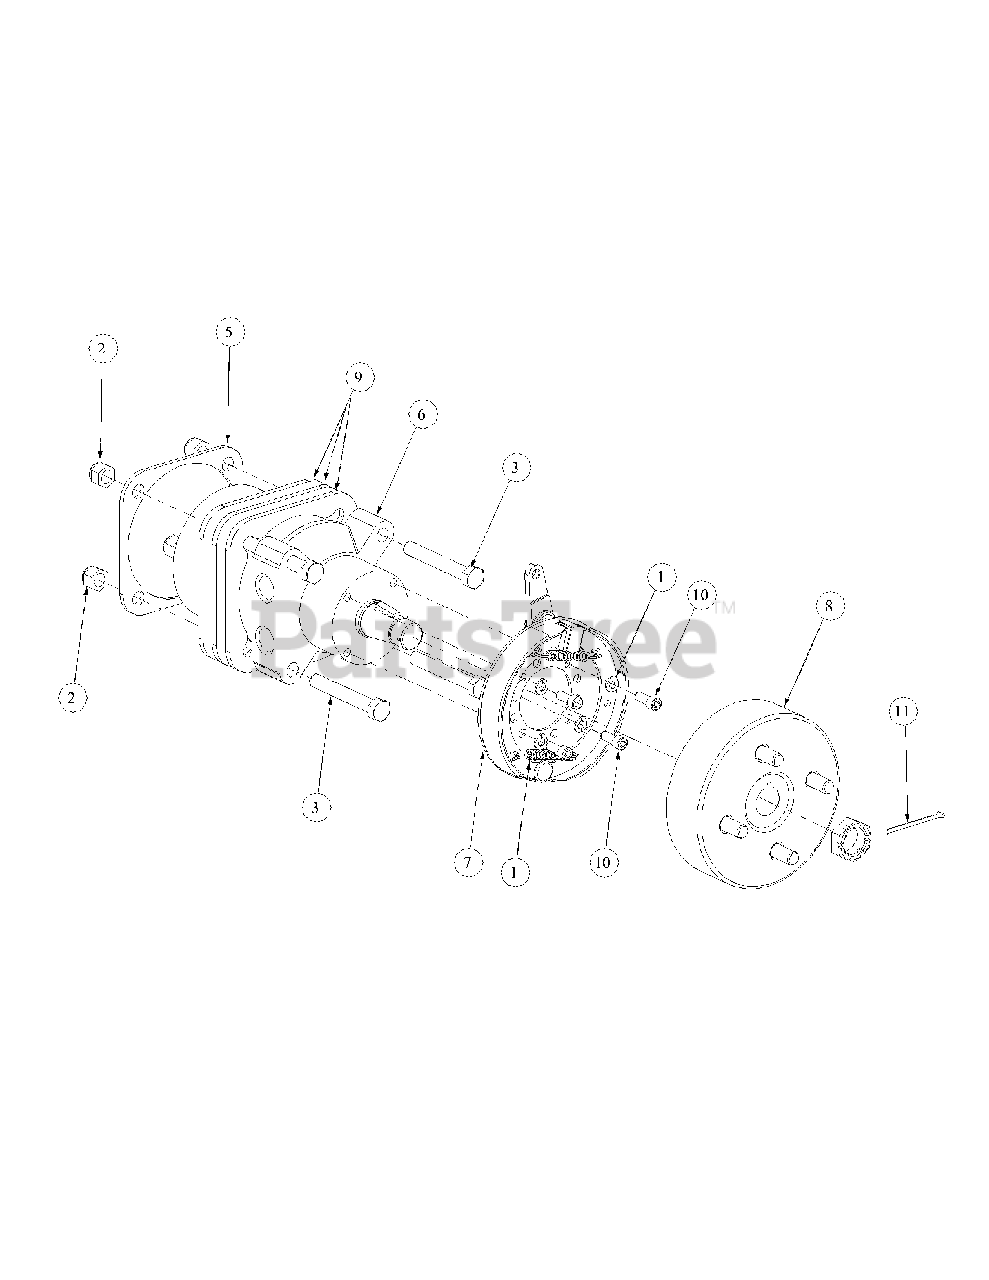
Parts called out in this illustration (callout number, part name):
1	Lock Washer, 5/16
2	Lock Nut, Nylon Insert, 1/2-13
3	Capscrew, 1/2-13 x 3.5
4	Hyd. Motor, Left Hand
5	Motor Plate
6	Hydro Motor, Right Hand
7	Brake Assembly w/Line
8	Hub and Drum Assembly w/Studs
9	Motor Spacer
10	Capscrew w/Socket, 5/16-18 x 3/4
11	Cotter Pin 5/32 x 1-1/2
